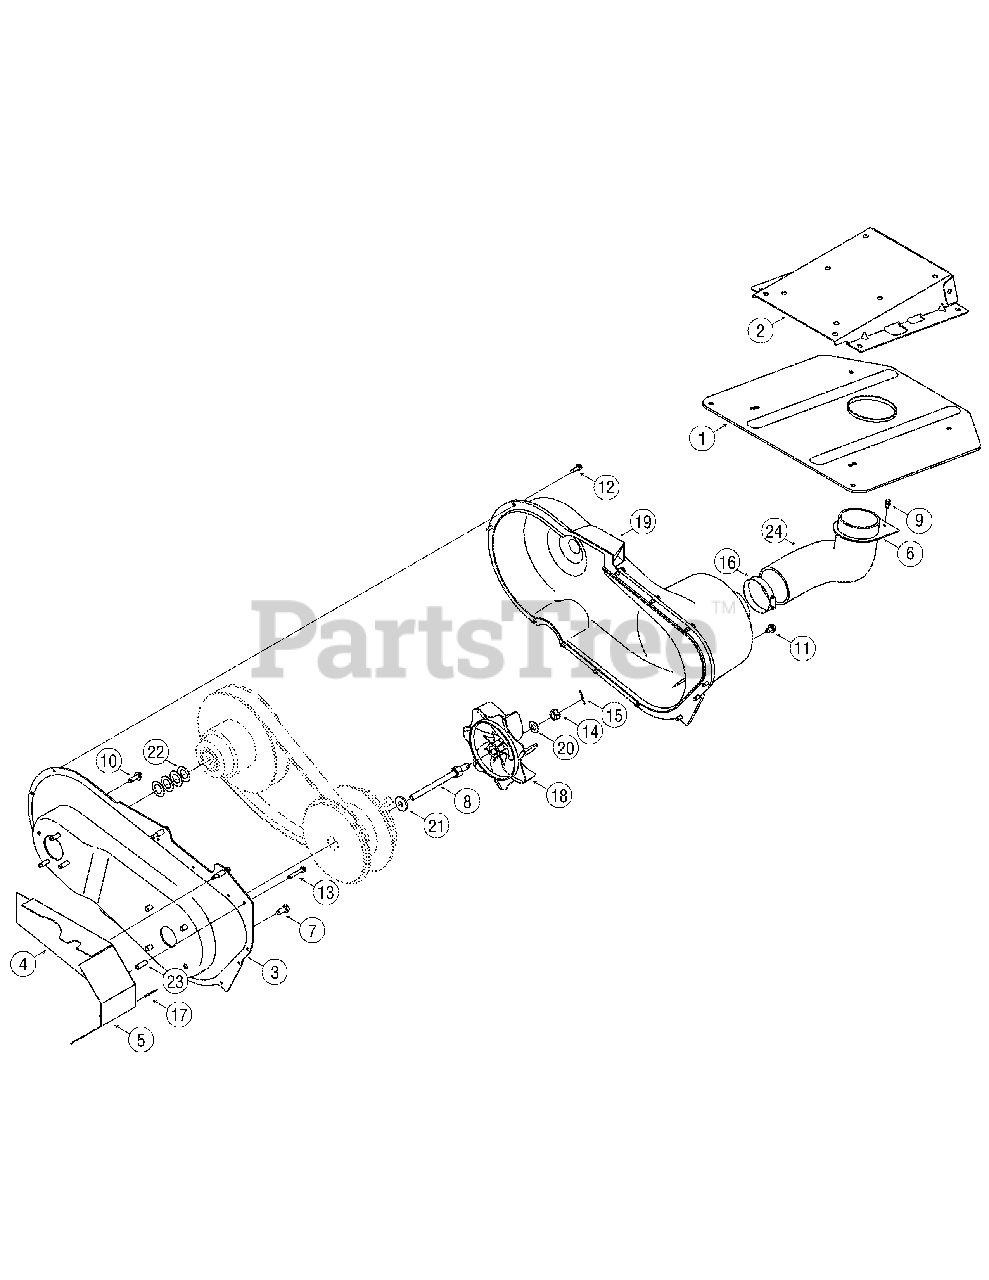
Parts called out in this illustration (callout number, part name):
3	Cvr, Back, Kohler
4	Cvr, Eng, Kohler
5	Cvr, Eng, Rear, Kohler
7	Hhcs, 3/8-16 x .75
8	Hhcs, 7/16-20 x 5.00
9	Scr, tt, 1/4-20 x .500
10	Scr, tt, 5/16-18 x 1.00
11	Screw, 5/16-12 x .500
12	Scr, tt, 1/4-20 x .750
13	Scr, tt, 1/4-20 x 1.625
14	Nut, Hex, 1/2-20
15	Pin, Cotter, 3/32 x 1.0
16	Clamp, Hose
16	Clamp, Hose, Adj
18	Impeller, Blo
19	Cvr, CVT, 4x4
20	Wash, Flat, .510 x 1.00 x .060
21	Wash, Flat, .450 x 1.250 x .164
22	Wash, Flat, .793 x 1.368 x .025
23	Spcr, .260 ID x .375 OD
24	Tube, CVT, Intake
